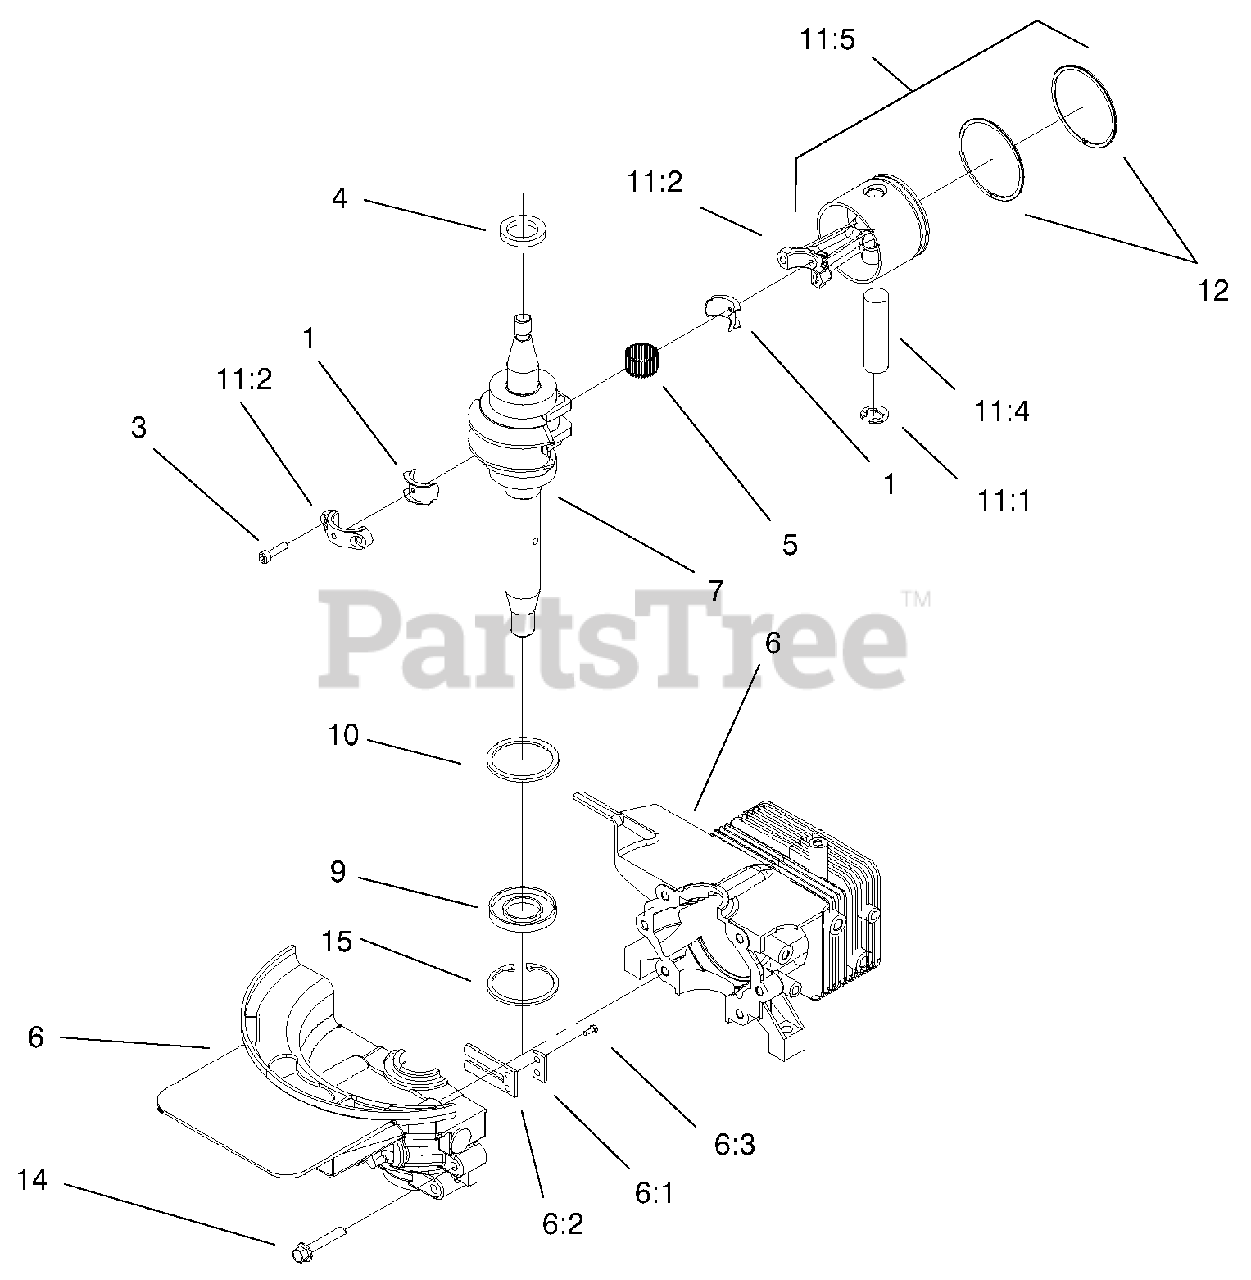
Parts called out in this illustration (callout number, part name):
1	Liner ASM
3	Screw-HSH
4	Seal-Oil
5	Bearing-Needle
6	Cylinder And Crankcase ASM
6:1	Plate-Backup, Reed
6:2	Reed-Carburetor
6:3	Screw-HH
7	Crankshaft And Bearing ASM Service
9	Seal-Oil
10	Ring-Retaining
11	Piston And Connecting Rod ASM
11:1	Ring-Retaining
11:2	Connecting Rod ASM
11:4	Pin-Wrist
11:5	Piston And Rings ASM
15	Ring-Retaining
